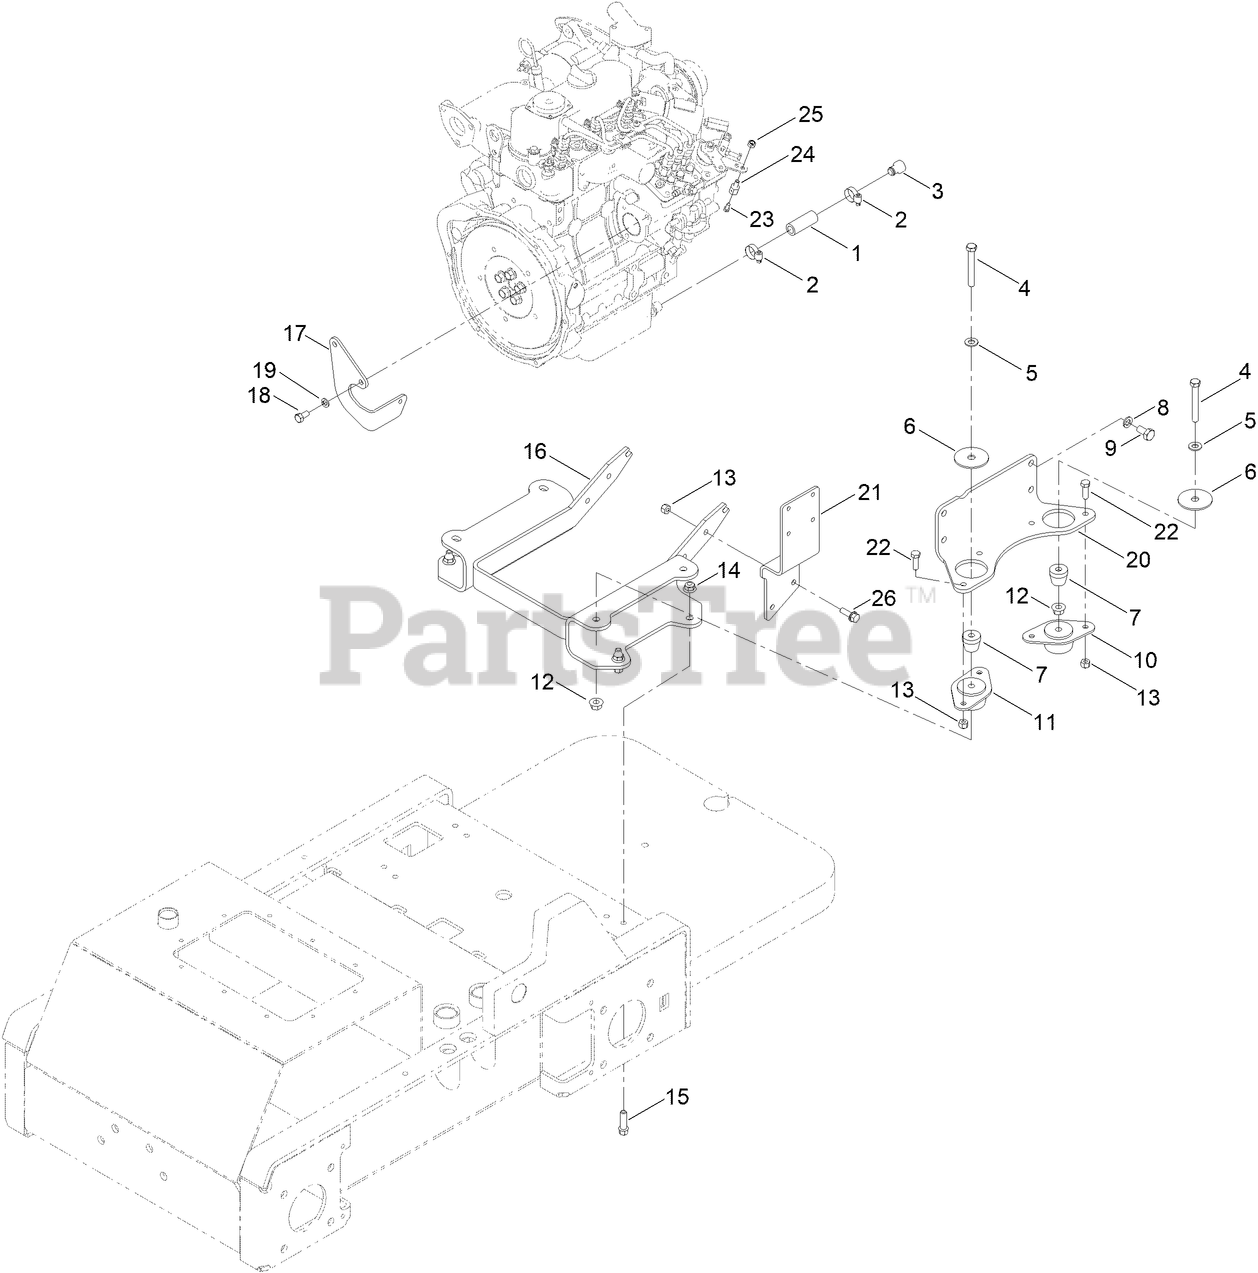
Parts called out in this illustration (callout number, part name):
1	HOSE-FUEL
2	CLAMP-HOSE
3	PLUG-OIL
4	SCREW-HH
5	WASHER-FLAT
6	WASHER-SNUBBING
7	SNUBBER-ENGINE MOUNT
8	WASHER-LOCK
10	MOUNT-ENGINE
11	MOUNT-ENGINE
12	NUT-LOCK, FLANGE
13	NUT-LOCK, NI
14	NUT-HF, NI
15	SCREW-TAPTITE
16	MOUNT-ENGINE
17	MOUNT-SOLENOID
18	BOLT
19	WASHER-LOCK
20	PLATE-MOUNT, ENGINE
21	MOUNT-FILTER, FUEL
22	SCREW-HH
23	SCREW-HH
24	SWIVEL-CABLE, THROTTLE
25	NUT-LOCK, NI
26	SCREW-HHF
